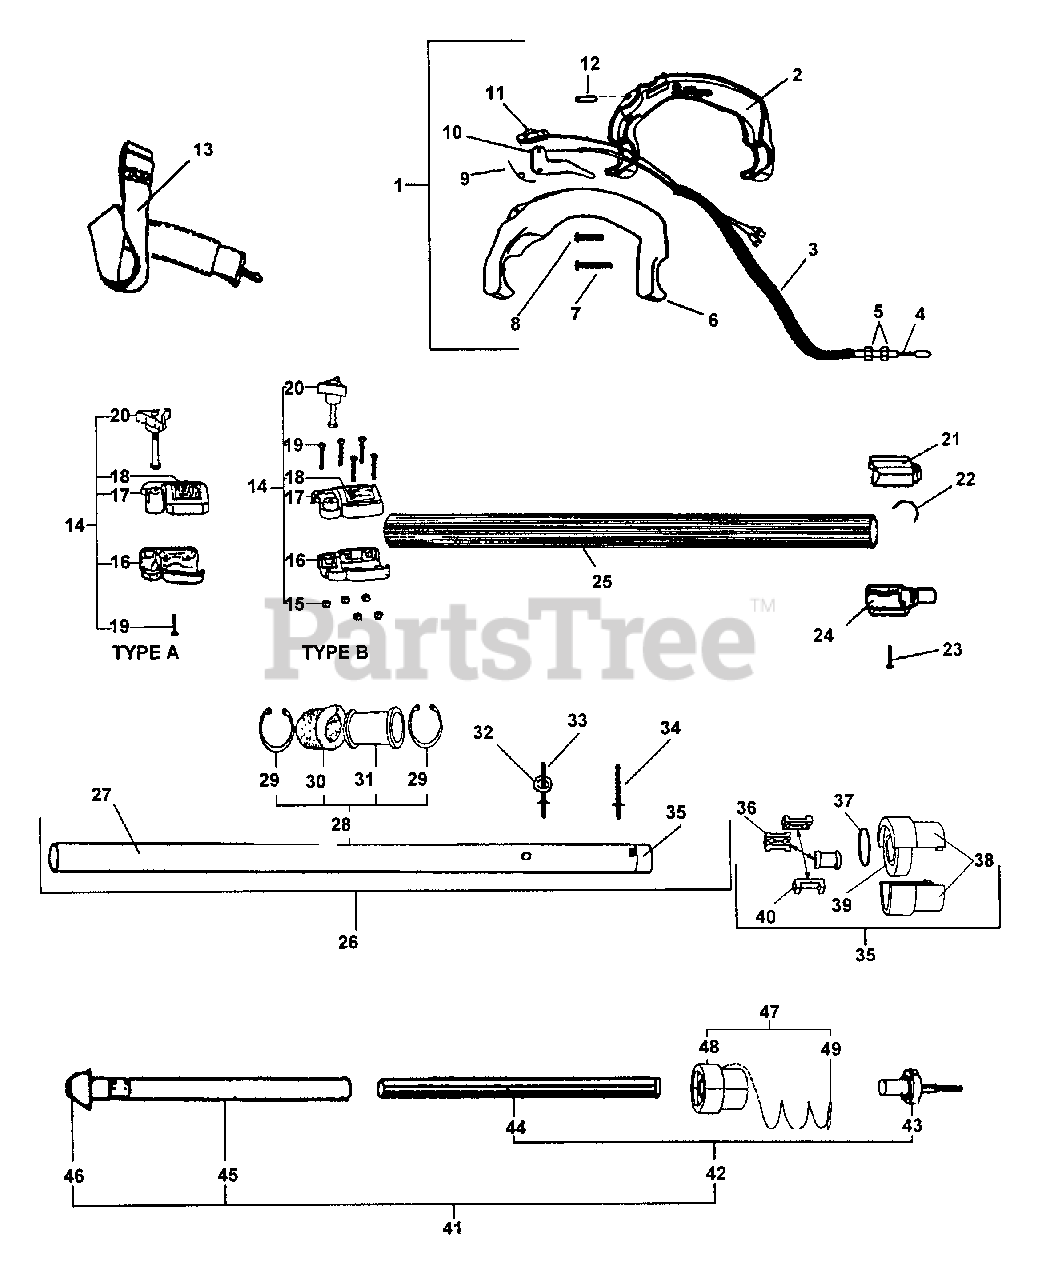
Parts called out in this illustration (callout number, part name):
1	HANDLE ASSY - REAR
2	HANDLE, REAR - RIGHT
3	TUBE, PROTECTIVE - CORRUGATED
4	CABLE, THROTTLE
6	HANDLE, REAR - LEFT
7	SCREW - 10-24 X 1-1/4"
8	SCREW - 10-24 X 7/8"
9	SPRING, TRIGGER
10	TRIGGER, THROTTLE
11	IGNITION SWITCH ASSY
12	PIN - LOCATING
13	SHOULDER STRAP ASSY
14	COLLAR ASSY
15	LOCKNUT - 10-24
16	COLLAR, MAIN PIPE - LOWER
17	COLLAR, MAIN PIPE - UPPER
18	LABEL - CAUTION
19	SCREW - 10-24 X 1-1/4"
20	THUMBSCREW
21	LOWER HSNG ADAPT (TOP)
23	SCREW - 10-24 X 1-1/4"
24	ADAPTER - LOWER
25	PIPE, MAIN - ORANGE
26	MAIN PIPE ASSY
27	PIPE, MAIN - BLACK
28	DRIVESHAFT GUIDE ASSY
29	RING, RETAINING
30	PAD, FOAM
31	GUIDE, DRIVESHAFT
32	WASHER - 5
35	BEARING HOLDER KIT
36	HOLDER, INNER BEARING - SMALL
37	WASHER - SPRING
38	BEARING HOLDER KIT
39	BEARING, BALL - 6002
40	HOLDER, INNER BEARING - LARGE
41	DRIVESHAFT ASSY
42	DRIVESHAFT - LOWER
43	CONNECTOR, SHAFT
44	DRIVESHAFT - LOWER
45	DRIVESHAFT - UPPER
46	ADAPTER, DRIVESHAFT - UPPER
47	FLOATING BUSHING ASSY
49	BUSHING, FLOATING
